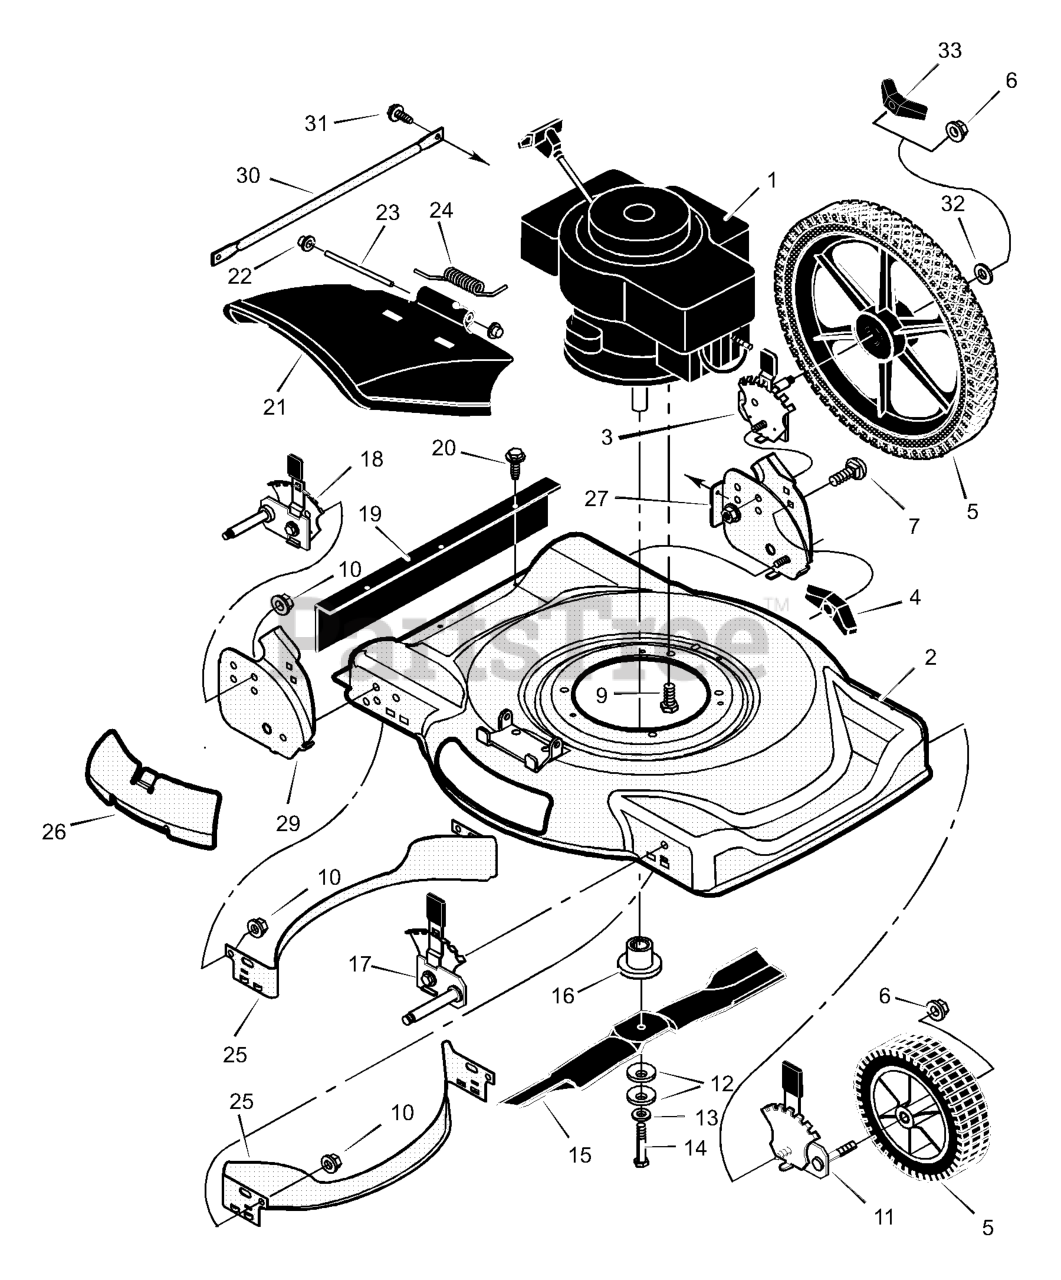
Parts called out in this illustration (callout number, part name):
1	Engine
2	Housing
3	Height Adjuster, Left Rear
5	Wheel and Tire, Front
6	Locknut, Flange
7	Bolt, Carriage
9	Bolt, Engine
10	Nut
11	Height Adjuster, Left Front
12	Washer, Belleville
14	Bolt, Hex
16	Adapter, Blade
17	Height Adjuster, Right Front
18	Height Adjuster, Right Rear
19	Guard, Rear
20	Screw
21	Deflector, Chute
22	Push-On Cap
23	Pin, Pivot
24	Spring
25	Baffle
26	Plate, Mulcher
27	Bracket, Left Handle
29	Bracket, Right Handle
33	Knob, Axle
